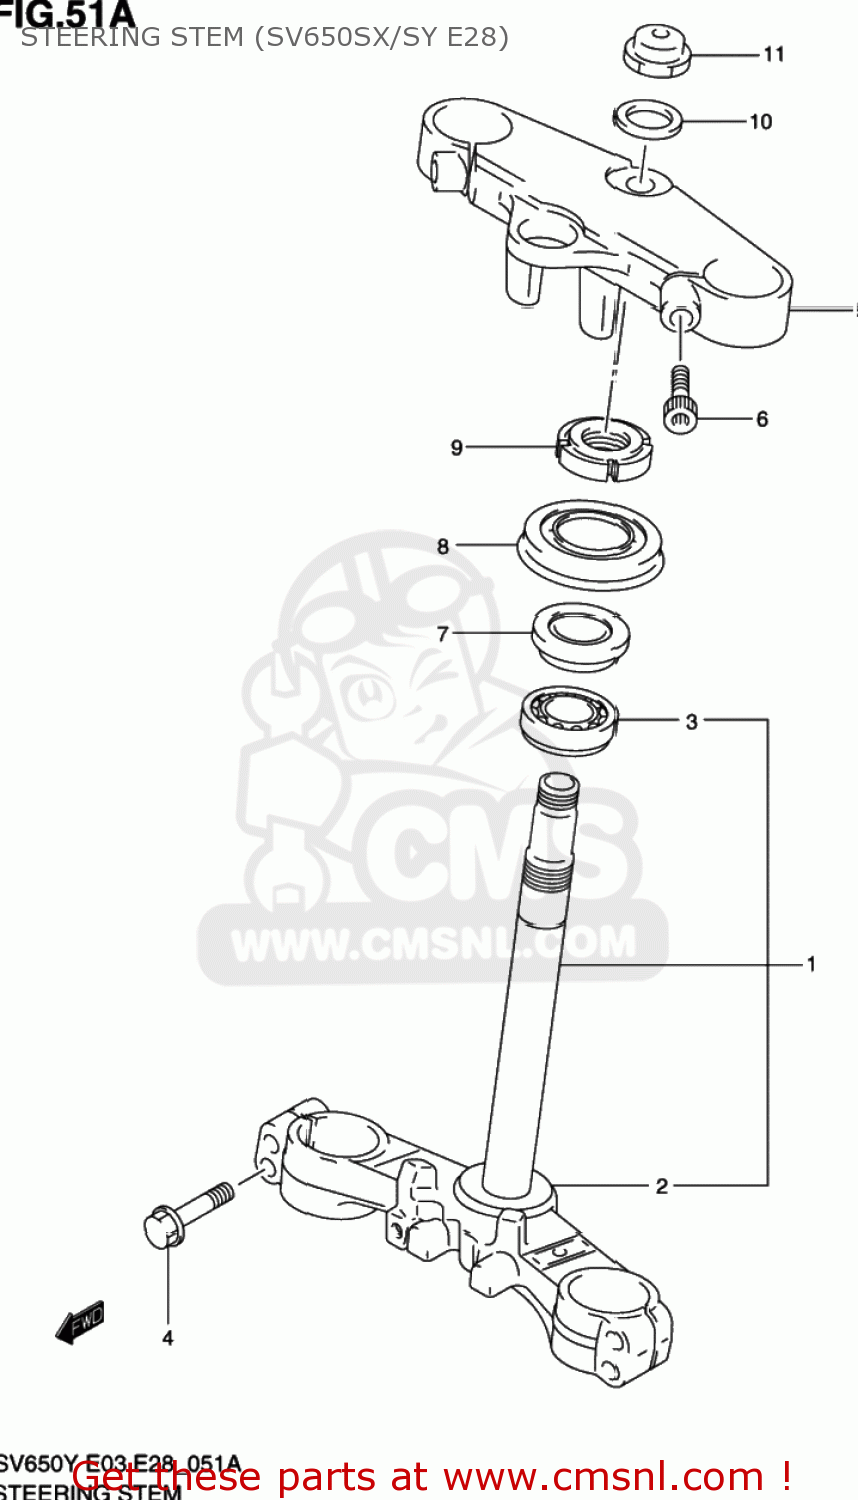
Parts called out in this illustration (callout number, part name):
1	STEM.STEERING
2	SEAL,STEERING LWR
3	BEARING(30X55X17)
4	BOLT
5	HEAD,STEERING STEM
6	BOLT(8X32)
7	BEARING(25X47X15)
8	SEAL,OIL(34X69X11.9)
9	NUT,STEERING STEM(25X44X10)
10	WASHER(22.5X35.9X1.6)
11	NUT
